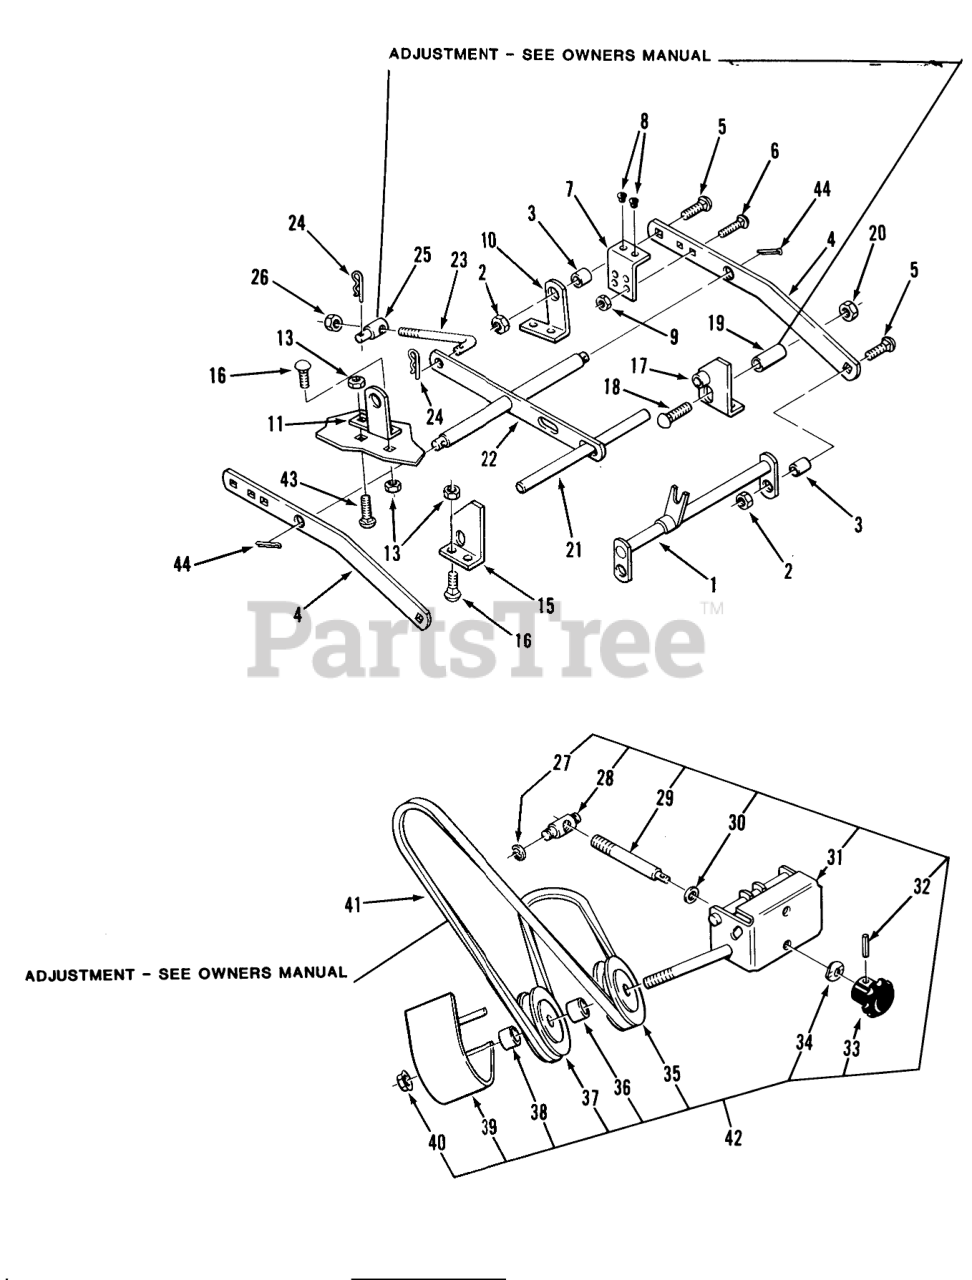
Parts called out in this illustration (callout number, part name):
1	Hitch
2	LOCKNUT-FLANGE
3	SPACER
4	Bar Draft
5	Bolt
6	Bolt-Carriage
7	Bumper-Metal
8	BUMPER-RUBBER
9	Nut
10	LH Rear Bracket
11	Rear Bracket RH
13	Nut
15	Front Bracket RH
16	Bolt-Carriage
17	Front Bracket LH
18	CARRIAGE BOLT -4
20	Nut
21	Front Shaft
22	Leveler
23	ROD-LEVEL ADJUST
24	Hairpin
25	TRUNNION-LIFT
26	NUT
27	RING-RETAINING
28	TRUNNION-DOUBLE
29	ROD ADJ
30	Washer
31	Front Support
32	PIN-ROLL
33	KNOB-ADJUSTMENT
34	WASHER-SPRING
35	Pulley-V
36	SPACER
37	PULLEY-FLAT IDLER
38	SPACER-OUTER
39	Belt Cover
40	Nut
41	V-BELT
42	ASM-SUPPORT,IDLER
43	Bolt
44	Cotter Pin
